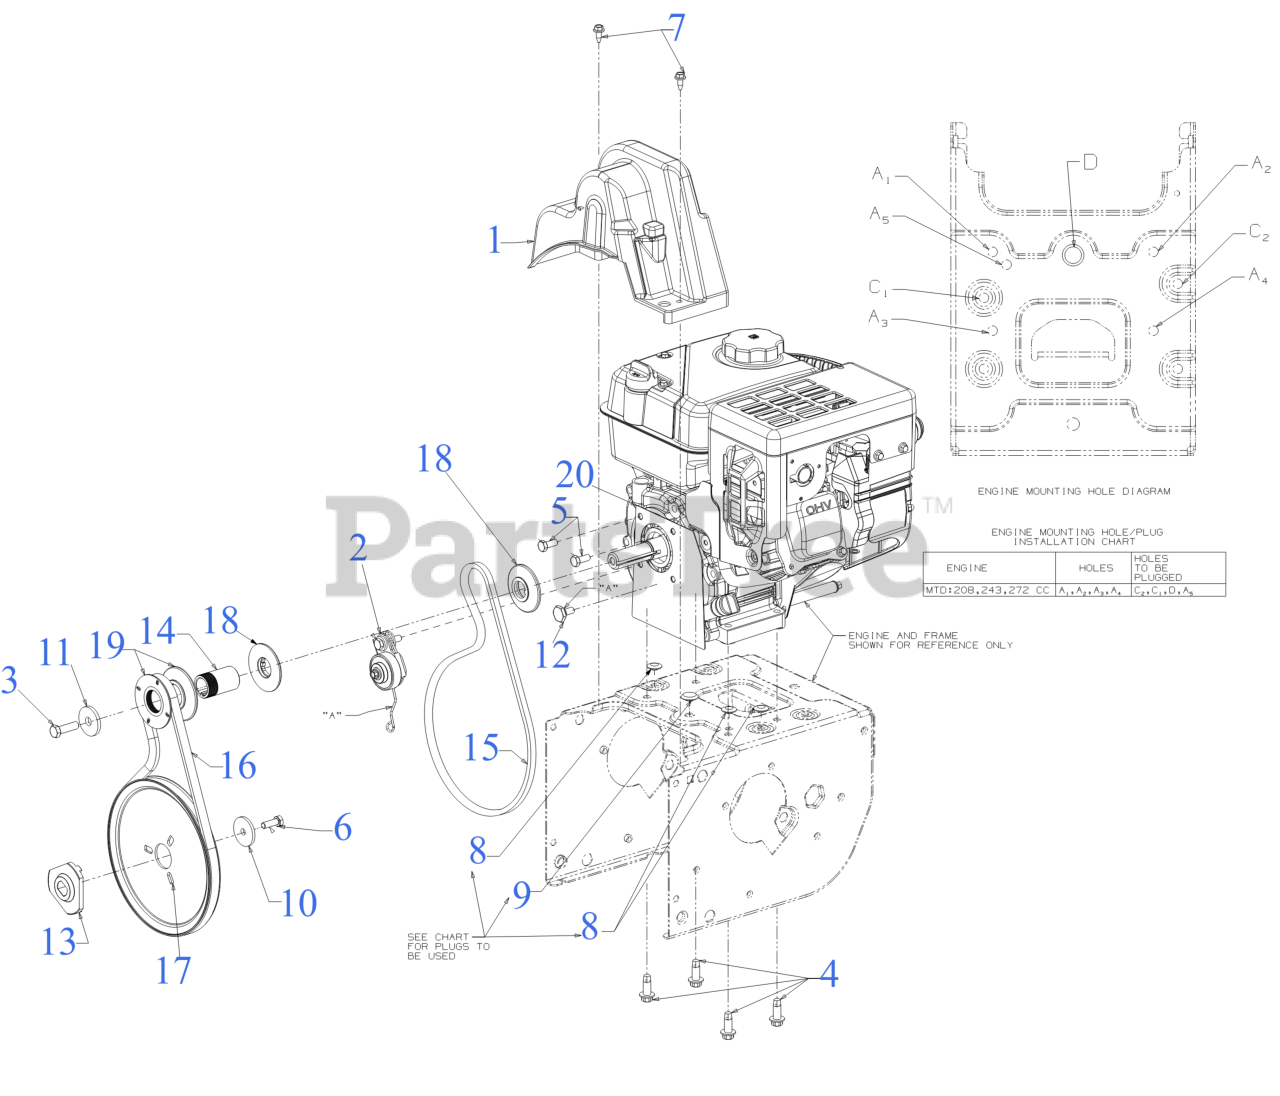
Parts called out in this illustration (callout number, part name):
1	BELT COVER SERVICE KIT (631-05322)
1	HEX SCREW #12-16 x .50
2	IDLER ASSEMBLY
3	SCREW 3/8-24X1.25
4	SCREW 3/8-16 x 1
5	SCREW 5/16-24 x .750 GR5
6	SCREW 5/16-24 x .875 GR5
7	SCREW 1/4-20X.625
8	PLUG-3/8 DIA ID x 3/32
9	PLUG-1/2 ID x 3/32
10	FLAT WASHER
11	FLAT WASHER .45 x 1.5 x .172 HT
12	SHOULDER SCREW
13	ADAPTER PULLEY .75 DIA W/DD
14	PULLEY SPACER
15	V-BELT 3/8 x 35
16	V-BELT .500 x 35.00LG
17	AUGER PULLEY
18	HALF PULLEY 3/8-V x 2.2
19	HALF PULLEY A2.76 x 1.140 SPLINE
